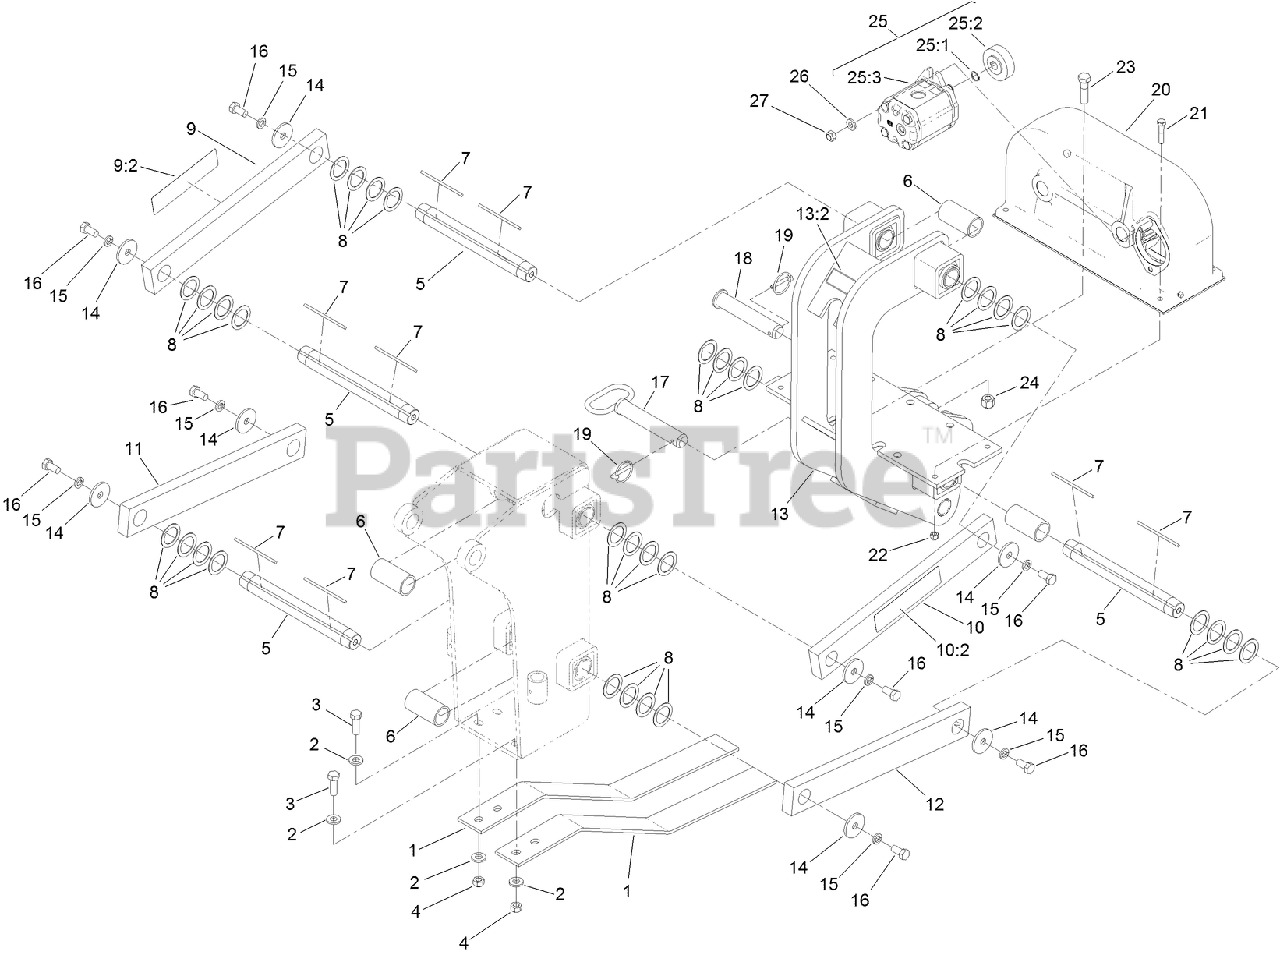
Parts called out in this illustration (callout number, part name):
1	SPRING-SHOE
3	SCREW-HH
4	LOCKNUT
5	SHAFT-MOUNTING, PLOW ARM
6	TUBE-SPACER
7	KEY-SQUARE
8	SHIM-ARM
9	RH UPPER BAR AND DECAL ASM
9:2	DECAL-DANGER, PLOW
10	LH UPPER BAR AND DECAL ASM
10:2	DECAL-DANGER, PLOW
11	ARM-PLOW, LOWER (RH)
12	ARM-PLOW, LOWER (LH)
13	MOUNTING BLADE AND DECAL ASM
13:2	DECAL-DANGER
14	WASHER-THRUST
15	WASHER-LOCK
16	SCREW-HH
18	PIN-MOUNTING, BLADE
19	PIN-KLIK
20	GEAR CASE ASM
21	SCREW-HH
22	NUT-HEX
25	HYD GEAR MOTOR ASM
25:1	RING-RETAINING
25:2	GEAR-MOUNTING, DRIVE
25:3	GEAR MOTOR ASM
26	WASHER
27	NUT-HEX
